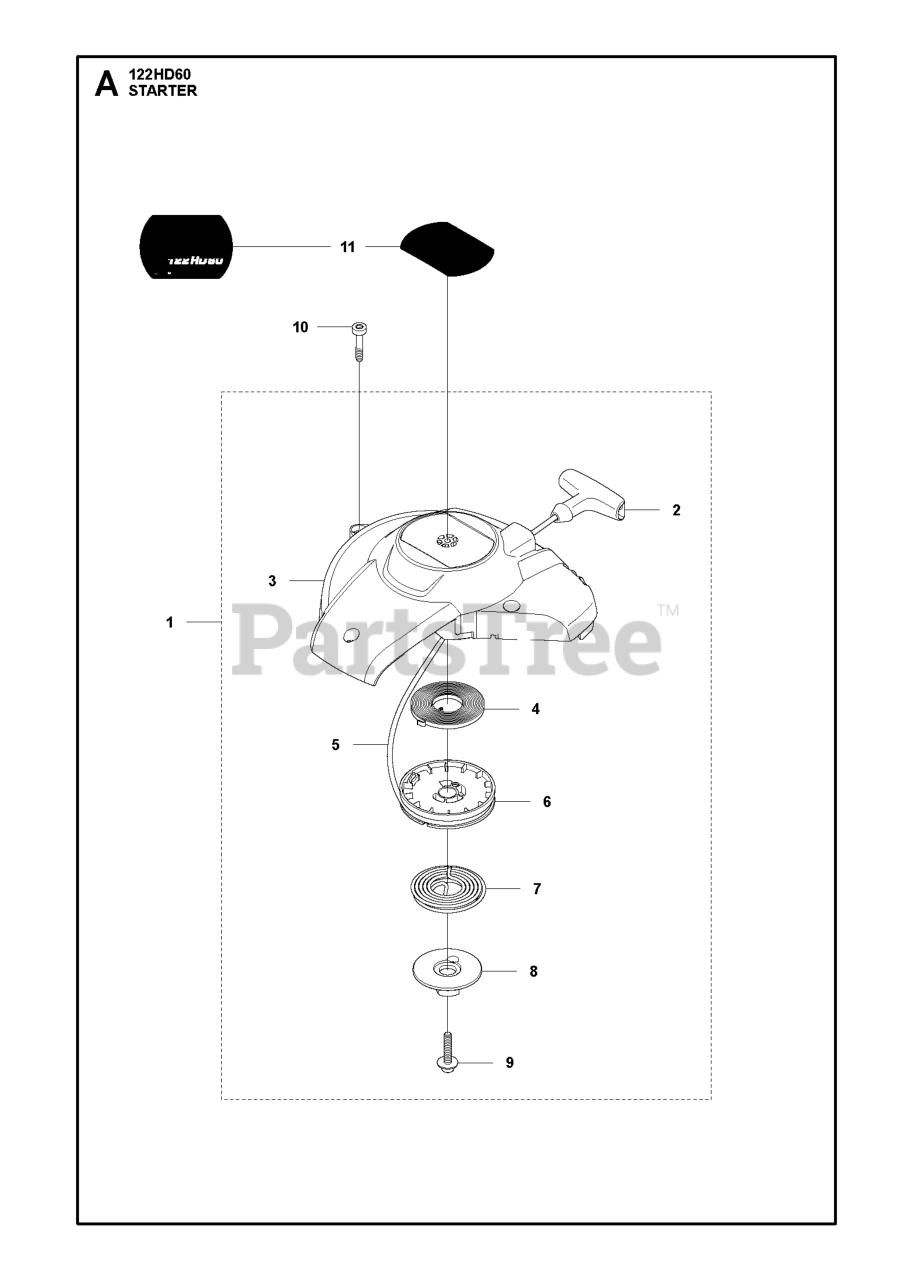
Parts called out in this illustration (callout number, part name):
1	STARTER ASSY.
2	STARTER HANDLE
3	STARTER HOUSING
5	STARTER CORD
6	STARTER PULLEY
10	SCREW CITXSCMO M5X25
11	DECAL, STARTER
